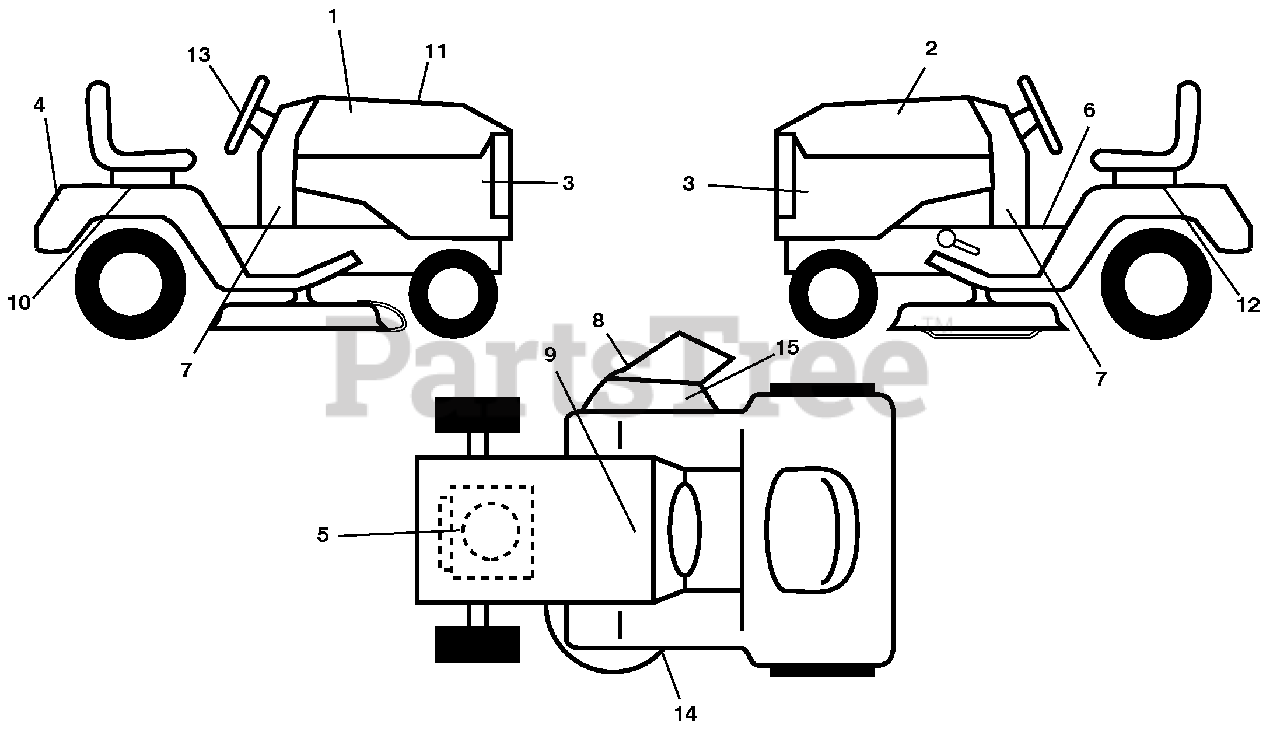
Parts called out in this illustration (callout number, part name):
1	Decal, Hood RH
2	Decal, Hood LH
3	Decal, Side Panel
4	Decal, Fender
5	Decal, Engine
6	Decal, Fender Operator's
7	Decal, Lower Dash
8	Decal, Warning
9	Decal, Battery Danger/Poison
10	Decal, Fender RH
11	Decal, Replacement
12	Decal Fender LH
13	Decal, Steering Wheel
14	Decal, Mower Schematic
15	Decal, Caution
15	Decal, Bypass
15	Pad, Foot Pedal Control
15	Pad, Footrest, LH
15	Manual, Operator's (Eng/French)
15	Manual, Parts
